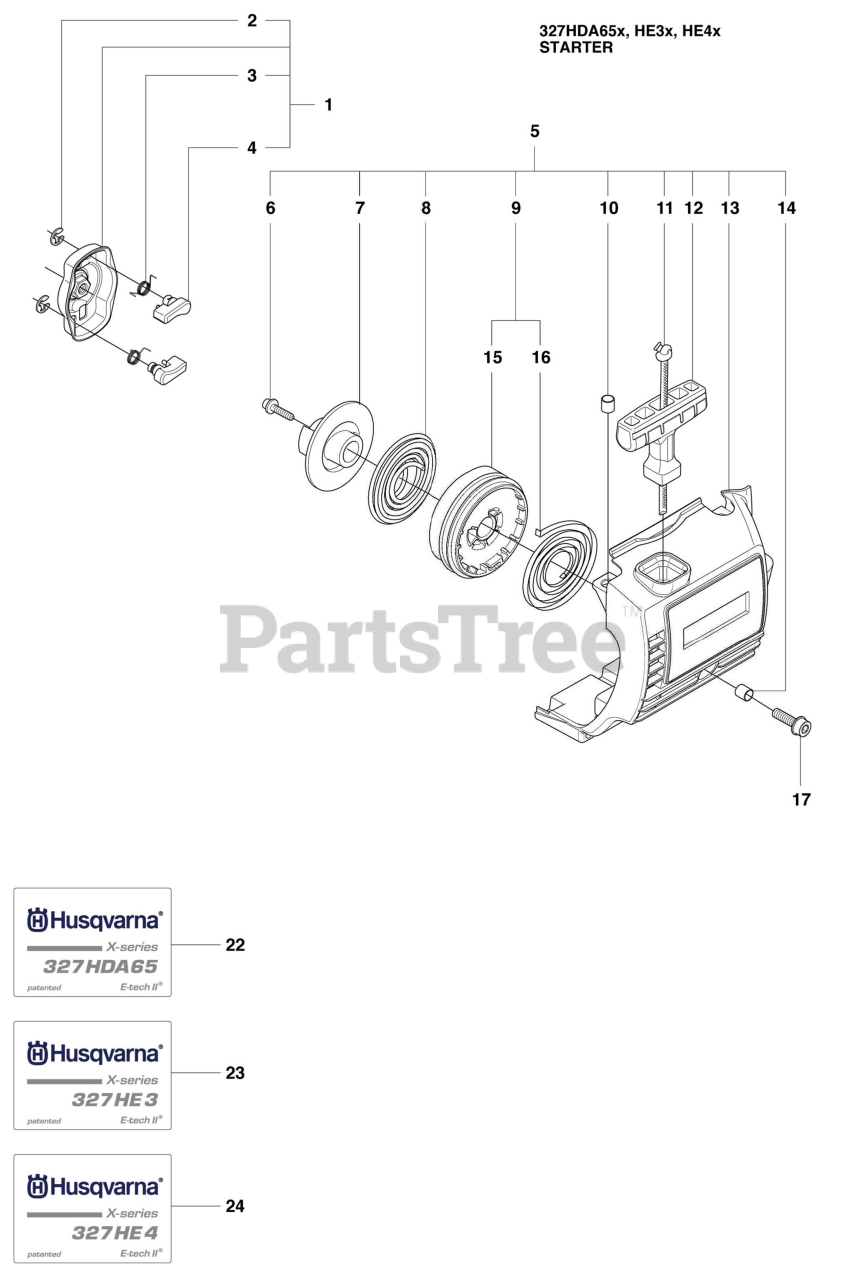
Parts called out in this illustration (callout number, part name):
1	Starter Pawl Bridge
2	Bar Retainer
4	Starter Pawl
5	Starter Assembly
7	Pulley Driver
8	Driver
9	Starter Pulley Assembly
10	Spacing Sleeve
11	Starter Rope
12	Starter Handle
13	Starter Housing
14	Spacing Sleeve
15	Starter Pulley
16	Spring
17	Screw, Ihscfm
22	LABEL STARTER 327HDA65
23	LABEL STARTER 327HE3
